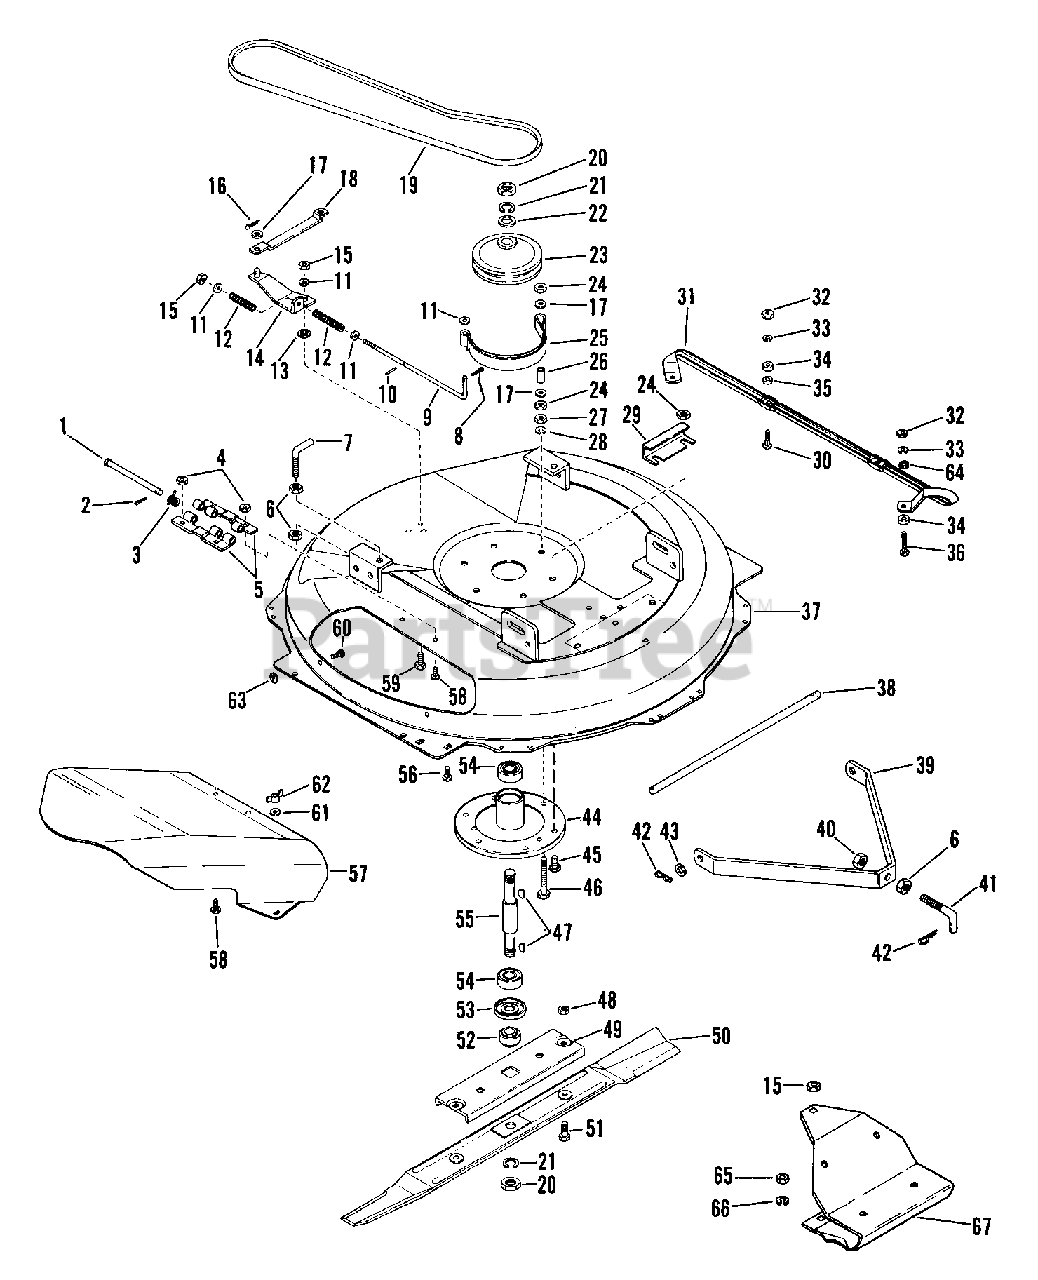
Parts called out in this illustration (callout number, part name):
1	CLEVIS PIN
2	PIN-COTR .09X.75 PL
3	SG-TORS .090X.37X.63
4	NUT-LK-CTR .250-20 PL
5	HINGE PLATE
6	NUT-JAM .50-13 PL
7	HANGER HOOK
8	PIN-COTR .06X.50
9	BRAKE ROD
10	PIN-ROLL .125X1.00
11	WSHR-FL-STL .323X.625X.062 PL
12	SG-COMP .057X.47X1.25
13	SPACER -FLANGED .325X.498X.318
14	BRAKE ACTUATOR
15	NUT-LK .312-18 GR A PL
16	PIN-COTR .12X1.0 PL
17	WSHR-FL-STL.406X.812X.065PL
19	V-BELT, 4L-RAW EDGE
20	NUT-JAM .75-10 PL
21	WSHR-LK .750X.188 MED PL
22	WSHR-FL-STL .755X1.250X.125
23	MOWER SHEAVE
24	NUT-LK-CTR .375-16 GR A PL
25	BRAKE BAND
26	SPACER .386X.502X1.060
27	NUT-HEX .375-16
28	WSHR-LK .375X.115 HVY PL
29	BRAKE BAND SUPPORT
30	BLT-RDHDSQNK .31-18X1.25 SHTPL
31	32 IN ADJUSTABLE SKID
32	NUT-HEX .312-18
33	WSHR-LK .312X.097 PL HVY
34	SPACER .328X.750X.375
35	SPACER BUSHING .5 X .32 X .21
36	BLT-RDHDSQNK .31-18X1.75 SHTPL
37	32 IN MOWER PAN SERVICE ASSEMB
37	32 IN MOWER PAN ASSEMBLY
38	TOW PIN
39	MOWER STRAP
40	NUT-LK-CTR .50-13
42	PIN-HAIR INT .09X.188 PL
43	WSHR-FL-STL .505X.880X.072 PL
44	SPINDLE HOUSING
45	BLT-HEX .38-16X.75 PL GR5
46	BLT-HEX .38-16X3.00 PL GR5
47	KEY-WDRF .188X.75X.313 SAE 9
48	NUT-LK TOP .375-16 GR C YWZC
49	BLADE TRAY
50	MOWER BLADE 32
51	BLT-HEX .38-16X1.00 PL GR5
52	RETAINER HUB
53	BEARING SLINGER
54	BRG-BALL .750X1.781X.61
55	SPINDLE SHAFT
56	BLT-RDHDSQNK .31-18X.75 GR5 PL
57	CHUTE DEFLECTOR W/ DECAL
58	BLT-RDHDSQNK .25-20X.62 PL
59	BLT-HEX .31-18X.75 PL GR5
60	BLT-RDHDSQNK .312-18X.62SHTPL
61	WSHR-FL-STL .328X.875X.062 PL
62	NUT-WING W/INSERT .312 - 18
63	NUT-PUSH .312
64	WSHR-FL-STL .438X1.125X.19
65	NUT-HEX .250-20 PL
66	WSHR-LK .250X.077 HVY PL
67	SKID -32" MOWER
